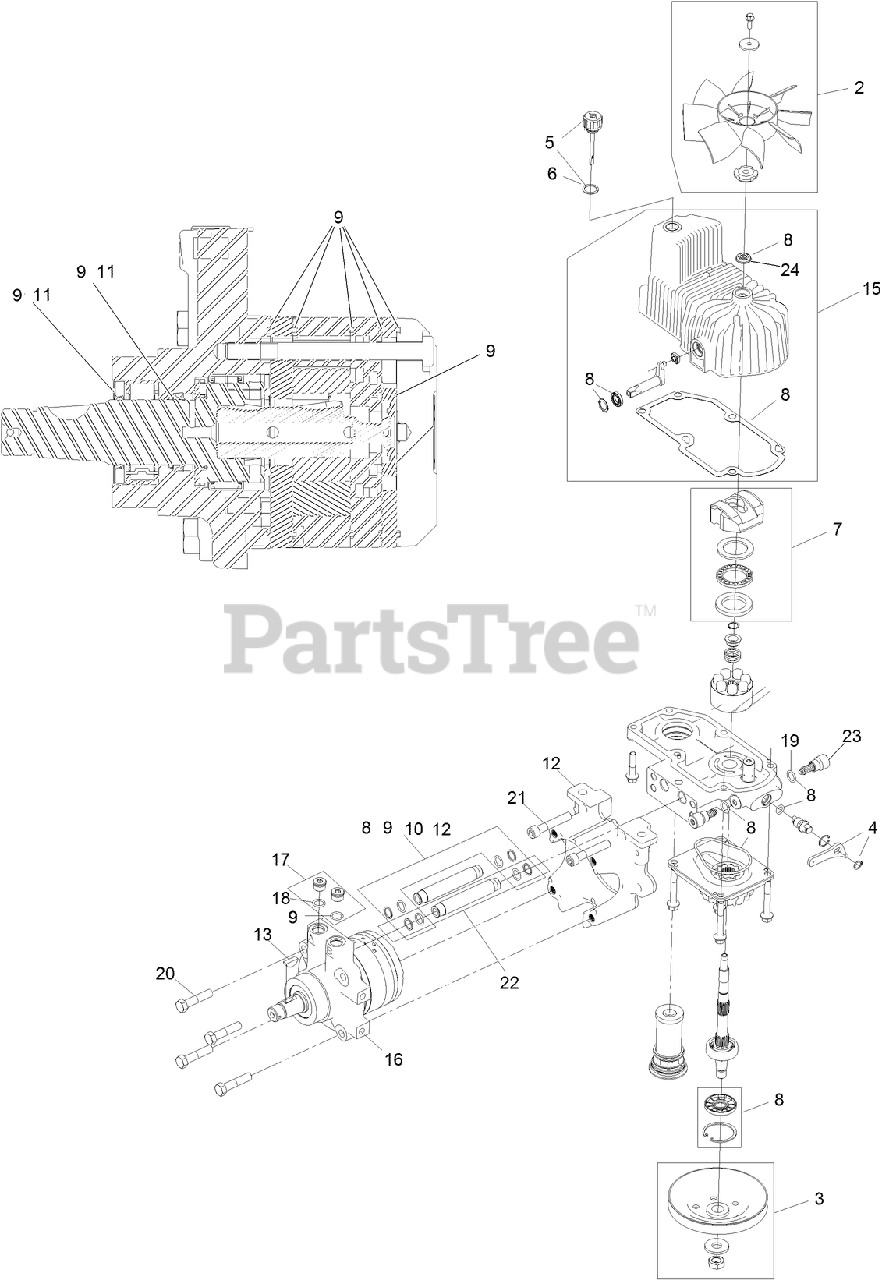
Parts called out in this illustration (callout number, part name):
2	FAN KIT
3	PULLEY KIT
4	HANDLE-BYPASS VALVE, HYDRO
5	DIPSTICK-HYDRO W/GASKET
6	GASKET-DIPSTICK, HYDRO
7	SWASH BLOCK KIT
8	PUMP SEAL KIT
9	MOTOR SEAL KIT
10	TUBE SEAL KIT
11	OUTPUT SHAFT SEAL KIT
12	NOSE CUP-UHT
13	Key-Woodruff 5/16 x 1
15	Housing-LH
16	MOTOR-HYDRAULIC LH 240CC
17	MAGNETIC PLUGS SERVICE KIT
18	O-RING
19	O-RING-CHECK VALVE
20	SCREW-HH 1/2-20 X 2 1/4
21	SCREW-HSH 1/2-20 X 2 3/4
22	HYDRAULIC TUBE KIT
23	SHOCK VALVE, 12CC HYDRO
24	SEAL-FAN DRIVE
